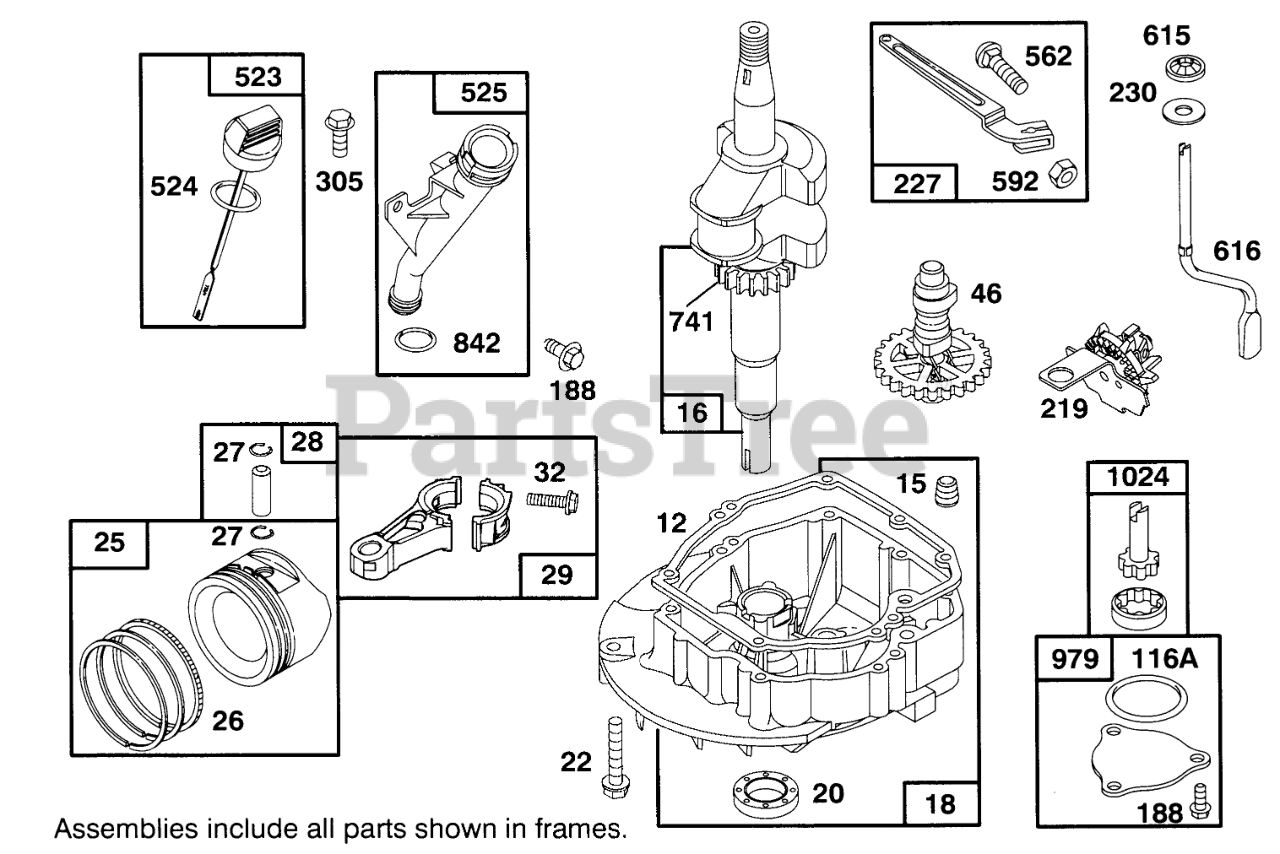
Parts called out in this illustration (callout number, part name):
12	ENGINE BASE GASKET
15	PIPE PLUG
16	Crankshaft
18	ENGINE SUMP
20	SEAL-OIL
22	SCREW - ENGINE BASE
25	STD PISTON ASSEMBLY
26	STD RING SET
27	PISTON PIN LOCK
28	PIN ASM - PISTON
29	CONNECTING ROD
32	SCREW - CONNECTING ROD
46	CAM GEAR
116A	O RING SEAL
188	Screw-Cap
219	GOVERNOR/OIL SLINGER
227	GOVERNOR LEVER ASSEMBLY
230	WASHER
305	SCREW - HEX HEAD
523	DIPSTICK-OIL
524	O-RING
525	OIL FILLER TUBE
562	GOVERNOR LEVER BOLT
592	HEX NUT
615	FASTENER
616	GOVERNOR CRANK
741	TIMING GEAR
842	O-RING
979	OIL PUMP COVER
1024	OIL PUMP
